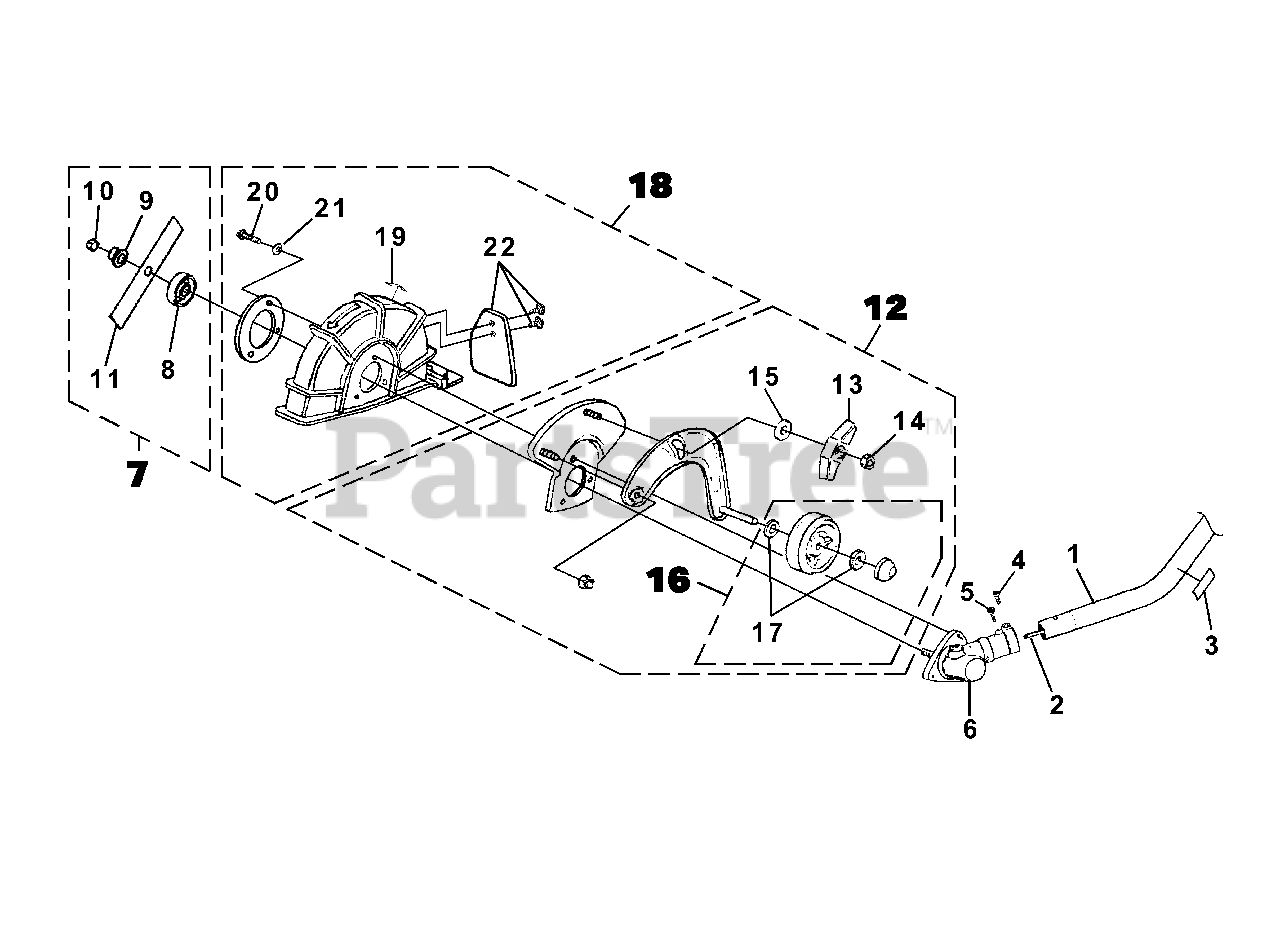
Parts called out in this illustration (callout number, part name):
1	DRIVESHAFT HOUSING
2	SHAFT-Flexible
3	DECAL-Warning
4	SCREW-Cap Socket Hd. (1/4-20 X 7/8")
5	SCREW-Sems Hex Hd. (10-24 X 1/2")
6	GEAR HEAD
7	BLADE KIT
8	WASHER-Flanged
9	WASHER-Flanged (Lower)
10	NUT-Lock
11	BLADE (2" X 9") (Qty.-2)
12	SUPPORT ARM ASSEMBLY
13	KNOB-Adjusting
15	WASHER-Flat
16	WHEEL KIT
17	WASHER-Flat
18	GUARD KIT
19	DECAL-Warning
20	SCREW-Hex Hd. (10-24 X 5/8")
21	WASHER-Lock (#10)
22	FLAP KIT
